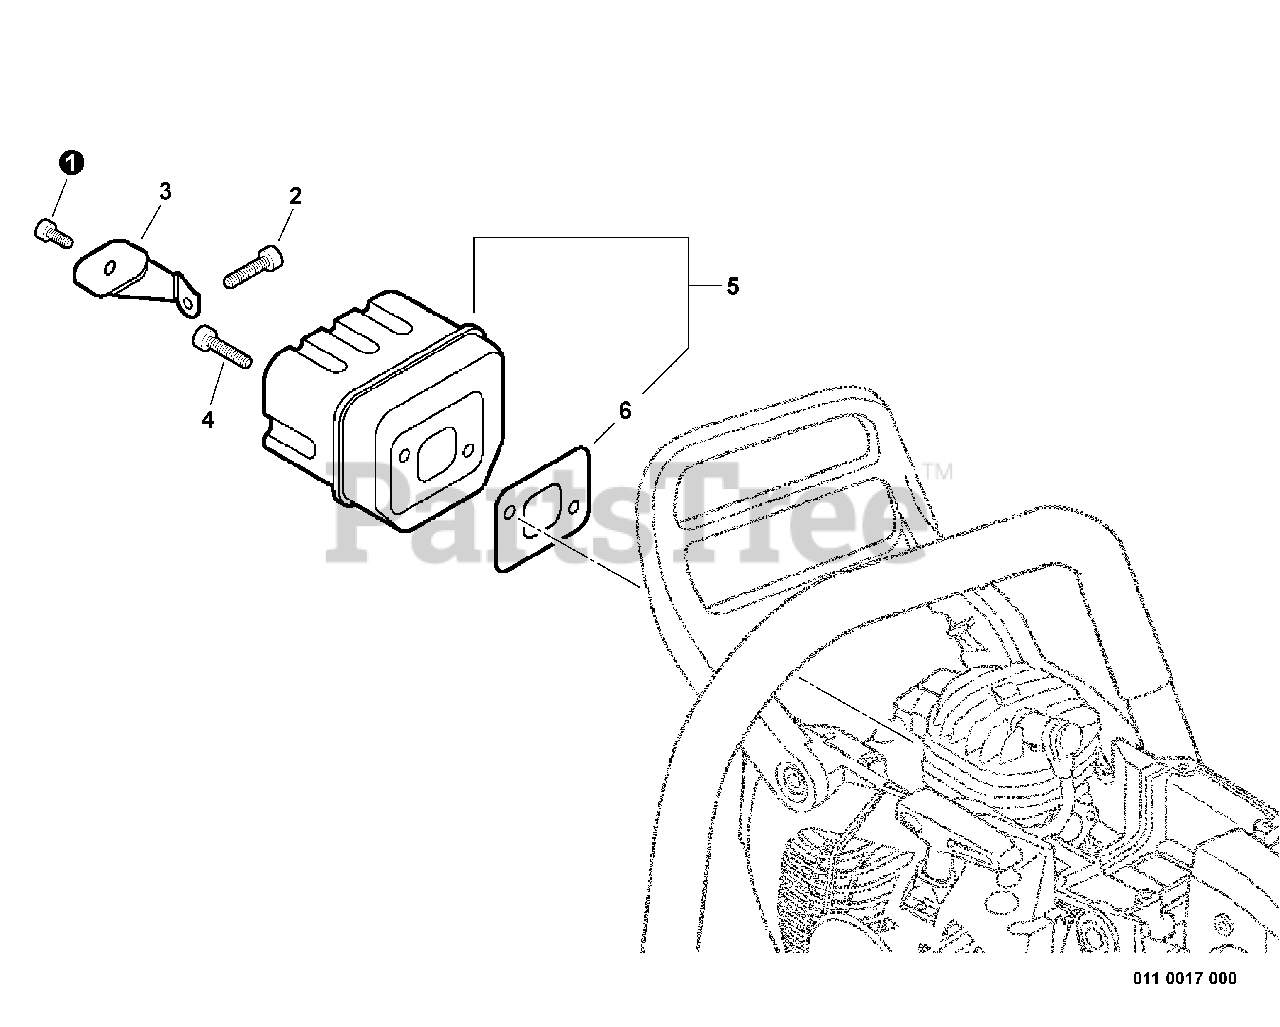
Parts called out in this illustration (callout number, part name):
2	SCREW - 6X14
3	BRACKET, MUFFLER
4	SCREW - 5X16
5	MUFFLER ASSY
6	GASKET, EXHAUST
